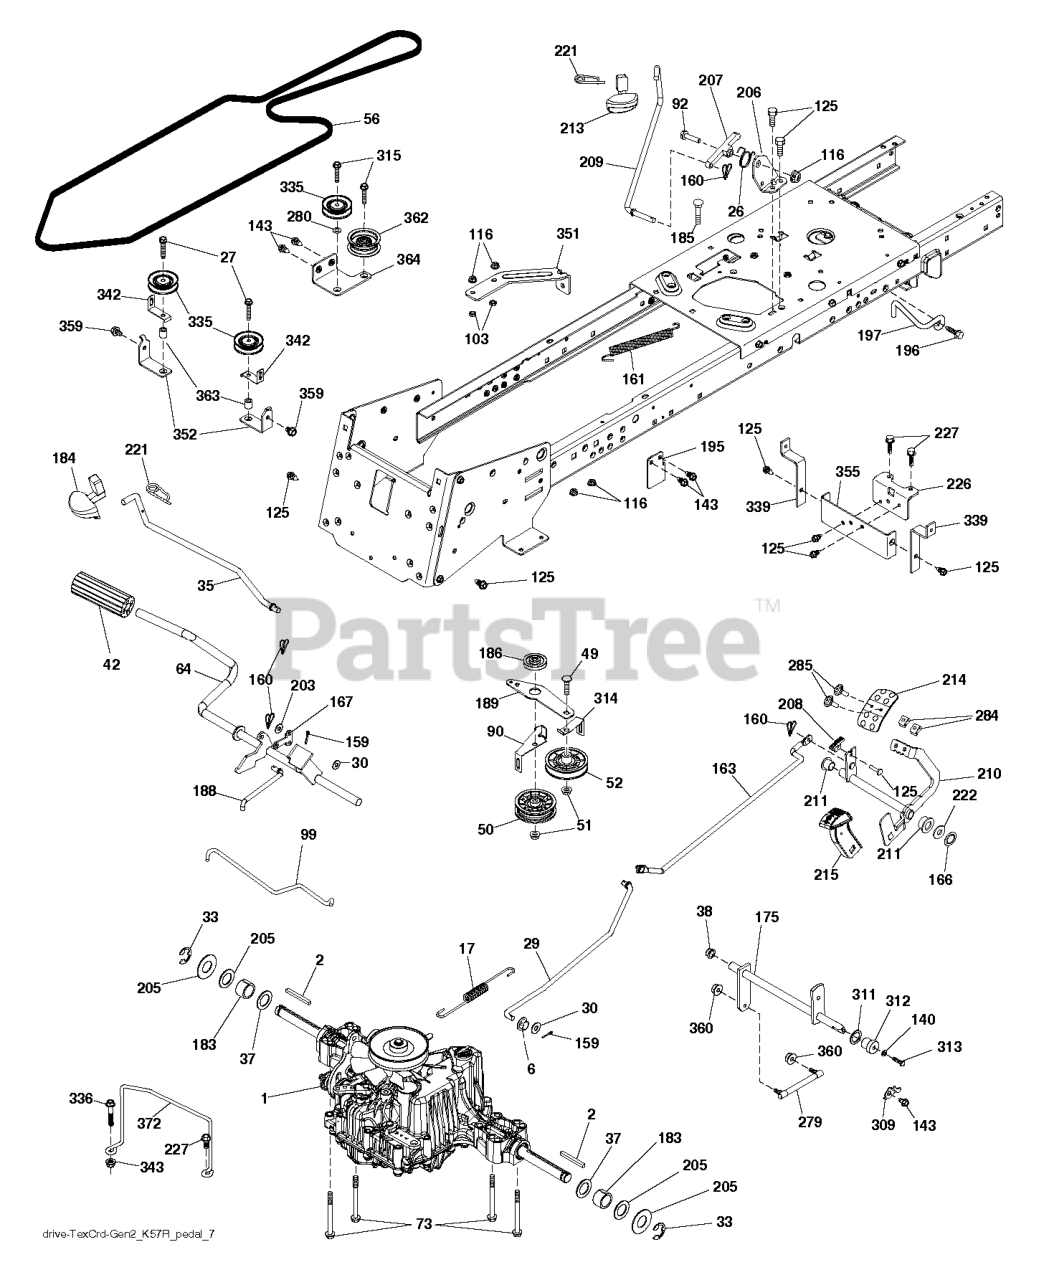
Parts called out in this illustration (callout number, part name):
2	SQUARE KEY
6	BUSHING.SNAP.NYL.BLK.
17	SPRING
26	SPRING.RETURN.CRUISE
27	SCREW
29	ROD ROD BRAKE K46 TCRD GEN 2
30	WASHER
35	ROD.BRAKE.PARTK.HUSQ.TEX
37	WASHER.HARDENED
38	NYLINER SNAP 5/8" ID
42	PEDAL COVER T
50	IDLER.FLAT.910.OFFSET
51	NUT LOCK FLG 3/8-16 UNC
52	IDLER.V-GROOVE.910.OFFSET
56	BELT BELT DRIVE GROUND 114.25
64	SHAFT.ASM.PEDAL.BRK.CNTR
73	BOLT HEX 5/16-18 GR 5
90	KEEPER KEEPER BELT CLUTCHING T
92	BOLT
99	ROD ROD BYPASS CRD TEX GEN 2
103	JAM NUT TI
116	NUT LOCK HEX FLANGE 5/16-18
125	SCREW
140	LOCKWASHER
143	Screw 5/16-18 x 1/2 Hex, Self Tapping 5/16-18 x 1/2
159	COTTER PIN
160	RETAINER CLIP
161	SPRING, RETURN LT
163	ROD ROD CONTROL SHIFT PEDAL TC
166	NUT.PUSH.625
167	LATCH.BRAKE.SPRING
175	SHAFT SHAFT CROSS SHIFT REAR F
183	SPACER AXLE
184	HANDLE.PARKING.BRAKE.H (BLK)
186	SPACER.RETAINER
188	LINK.CLUTCH.GROUND DRIVE.LONG
189	BELLCRANK BELLCRANK GROUNDDRI
195	BRACKET.ROD.BRAKE
196	SCREW 3/8-16X1
197	CLUTCH.ANTIROTATION.WIREFORM.
203	WASHER
206	BRACKET.MOUNT.CRUISE.LATCH
207	LATCH.CONTROL.CRUISE.TEX
208	GEAR.SECTOR.CONTROL.CR
209	ROD.CONTROL.CRUISE.GT.
210	ROCKER.ASM.PEDAL.CONTR
211	BEARING.NYLON
213	KNOB.CONTROL.CRUSIE.HU
214	PEDAL.FORWARD.HUSQVARNA.DEALER
215	PEDAL.COVER.REVERSE.CRD.X428BK
221	RETAINER.SPRING.CLIP.H
222	WASHER 21/32 X 1-1/4 X 10 GA.
226	BRACKET.MOUNT.TORQUE.K46.TLT
227	SCREW.THDROL.5/16-18X3/4.TTY
279	LINK SUBASM. LINK AND STUD
280	WASHER T
284	NUT.U-CHNL.1/4-20.550DP.350PNL
285	SCREW.MACHINE.CR.1/4-20
309	PLATE.FASTENING.CROSS.SHAFT
311	WASHER NYL
312	HUB.TAPERED.ROUND.CRD
313	BOLT
314	RETAINER KEEPER BELT
315	BOLT.5/16-18X1.25
335	PULLEY.V-IDLER.
336	BOLT.5/16-18X1-3/4.FLANGED.HEX
339	STRAP STRAP TORQUE K46 CRD TE
342	BELT GUIDE
343	5/16-18 NYLOC FLANGE NUT
351	BRACKET BRACKET DECK SWAY
352	BRACKET BRACKET IDLER CRD TEX
355	STRAP STRAP TORQUE K46 CRD TEX
359	SCREW LT.3/8-46X5/8
360	NUT NUT HEX CENTERLOCK 5/16-24
362	IDLER.FLAT.2.25.INCH
363	SPACER SPACER 343X63X.62
364	BRACKET BRACKET IDLER CRD TEX
372	KEEPER.BELT.CRD2.K46.2.BOLT.
